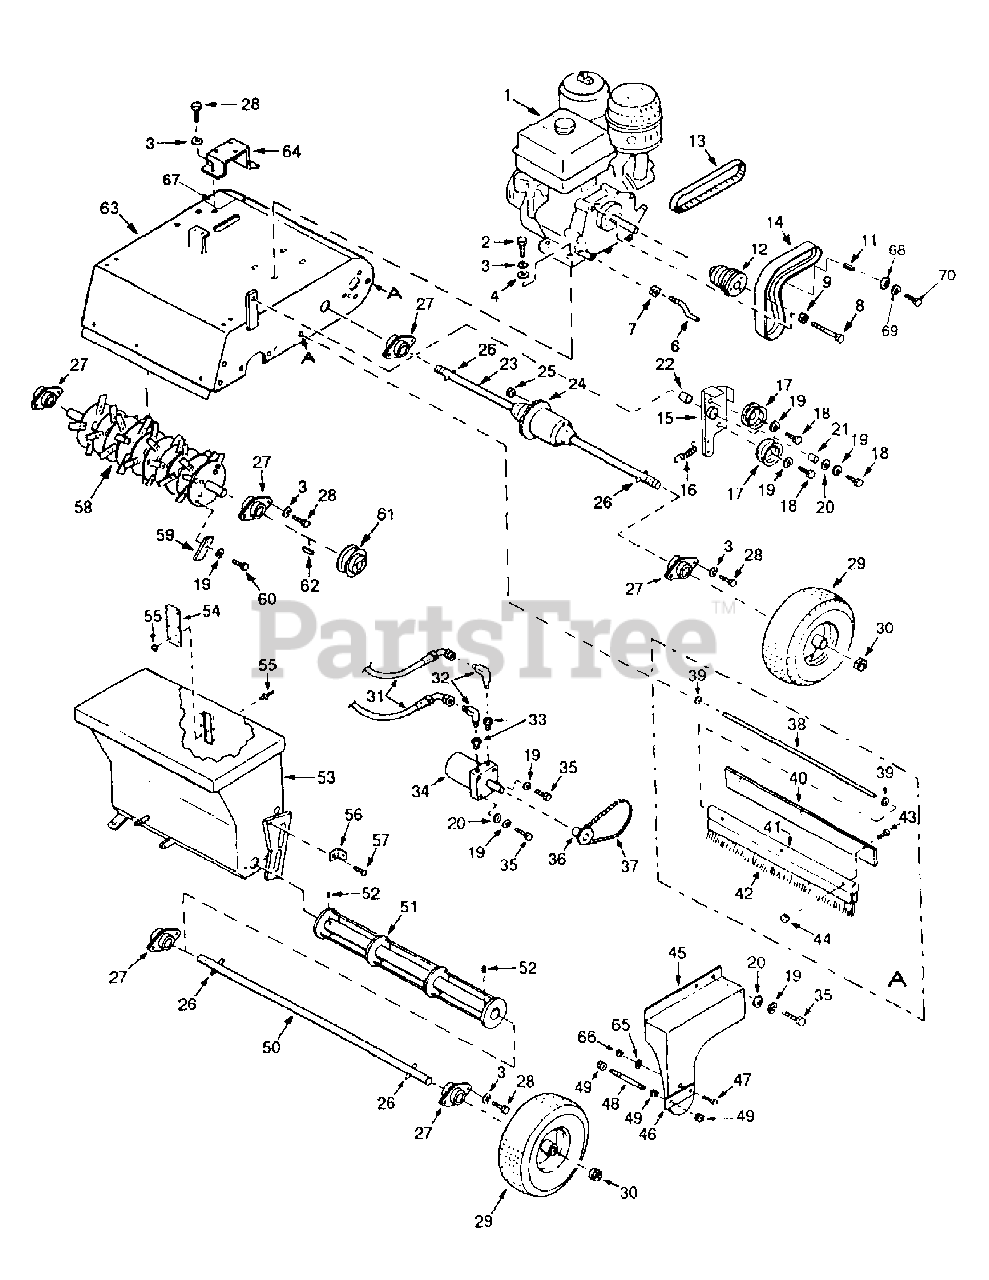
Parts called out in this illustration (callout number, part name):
1	Engine, Kawasaki, 8 HP
2	Cap Screw, 5/16-18 x 1-1/2 Hex Hd.
3	Lock Washer, 5/16
4	Flat Washer, 5/16
6	Belt Guide, Lower
7	Hex Nut, 3/8-16
8	Cap Screw, 5/16-24 x 4-1/2 Hex Hd.
9	Hex Nut, 5/16-24
11	Key, 1/4 x 1/4 x 1/4
12	Double Pulley, 2.65 Dia. 3.15 Dia.
13	Pump Belt
14	Belt, Blade Reel Drive
15	Bellcrank, Blade Reel Drive
16	Spring, Idler Tension
17	Idler Pulley
18	Cap Screw, 3/8-16 x 1-1/2 Hex Hd.
19	Lock Washer, 3/8
20	Flat Washer, 3/8
21	Pivot Tube, Bellcrank
22	Bushing
23	Differential and Axle
24	Sprocket, Machined
25	Hex Nut, 5/16-18 Nylock
26	Pin, Groove, 1/4 x 1-1/2
27	Flanged, Ball Bearing
27	Flange Cover, Bearing
28	Cap Screw, 5/16-18 x 3/4 Hex Hd.
29	Wheel and Tire Assembly
30	Nut, Jam 1.0-14 Insert Lock
31	Hydraulic Hose, Valve to Hyd. Motor
32	Hydraulic Fitting, 90§ Elbow
33	Hydraulic Fitting, Reducer
34	Motor, Hydraulic Drive
35	Cap Screw, 3/8-16 x 1 Hex Hd
36	Sprocket, Hydraulic Motor
37	Chain, Roller
38	Brush Shaft
39	Retainer, Push-On, 1/4
40	Brush Guard
41	Clip, Brush Support
42	Brush
43	Mach. Screw, #10-32 x 3/4 Rd. Hd.
44	Hex Nut, #10-32 w/Star Washer
45	Belt Guard
46	Bracket, Belt Guard
47	Cap Screw, 1/4-20 x 1/2 Hex Hd
48	Rod, Belt Guard Support
49	Hex Nut, 5/16 -18
50	Agitator Shaft
51	Agitator Assembly
52	Set Screw, 5/16-18 x 5/16 Soc. Hd
53	Hopper w/Cover
54	Plastic Window
55	Rivet w\Washer
56	Spring Bracket
57	Mach. Screw, #8-32 x 5/16 Truss Hd.
58	Renovator Reel
58	Disc Shaft
58	Blade Disc
58	Spacer, Blade Disc
58	End Spacer, Blade Disc
58	Hex Nut, 1-1/4-12 Stover
59	Blade, Heavy Duty
60	Cap Screw, 3/8-16 x 1/2 Hex Hd
61	Pulley, Blade Reel Drive
61	Pulley Bushing
62	Key, 1/4 x 1/4 x 1-1/4
63	Power Deck
64	Bracket, Valve Mount
65	Lock Washer, 1/4
66	Hex Nut, 1/4-20
67	Overlayment; Label;Clear
68	Clutch; Washer; Plated
69	Lock Washer; 7/16
70	Capscrew; 7/16-20 x 2
